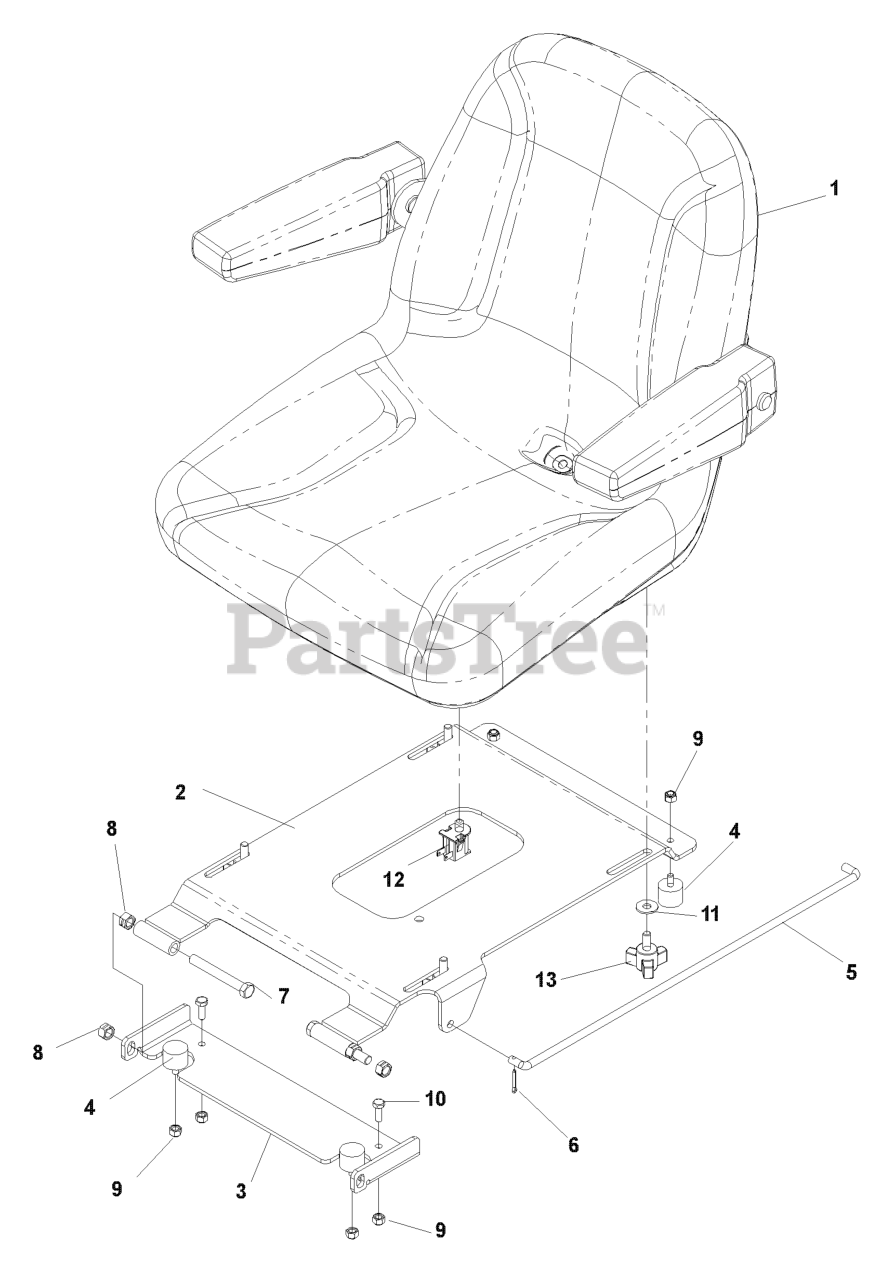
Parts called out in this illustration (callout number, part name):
1	SEAT W/ARMRESTS
2	SEAT PAN WLDMT
3	SEAT BRKT W/DECAL
4	STUD/PLATE MOUNT
6	RP_COTTER PIN 1/8 X 3/4
7	HCS 3/8C X 3
8	NUT 3/8C CENTERBLOCK
9	NUT.1/4-20.HEX.NYLOC.ZD
10	HCS 1/4C X 3/4 HCS
11	WASHER 5/16 FLAT
12	SEAT SWITCH
13	KNOB W/STUD
